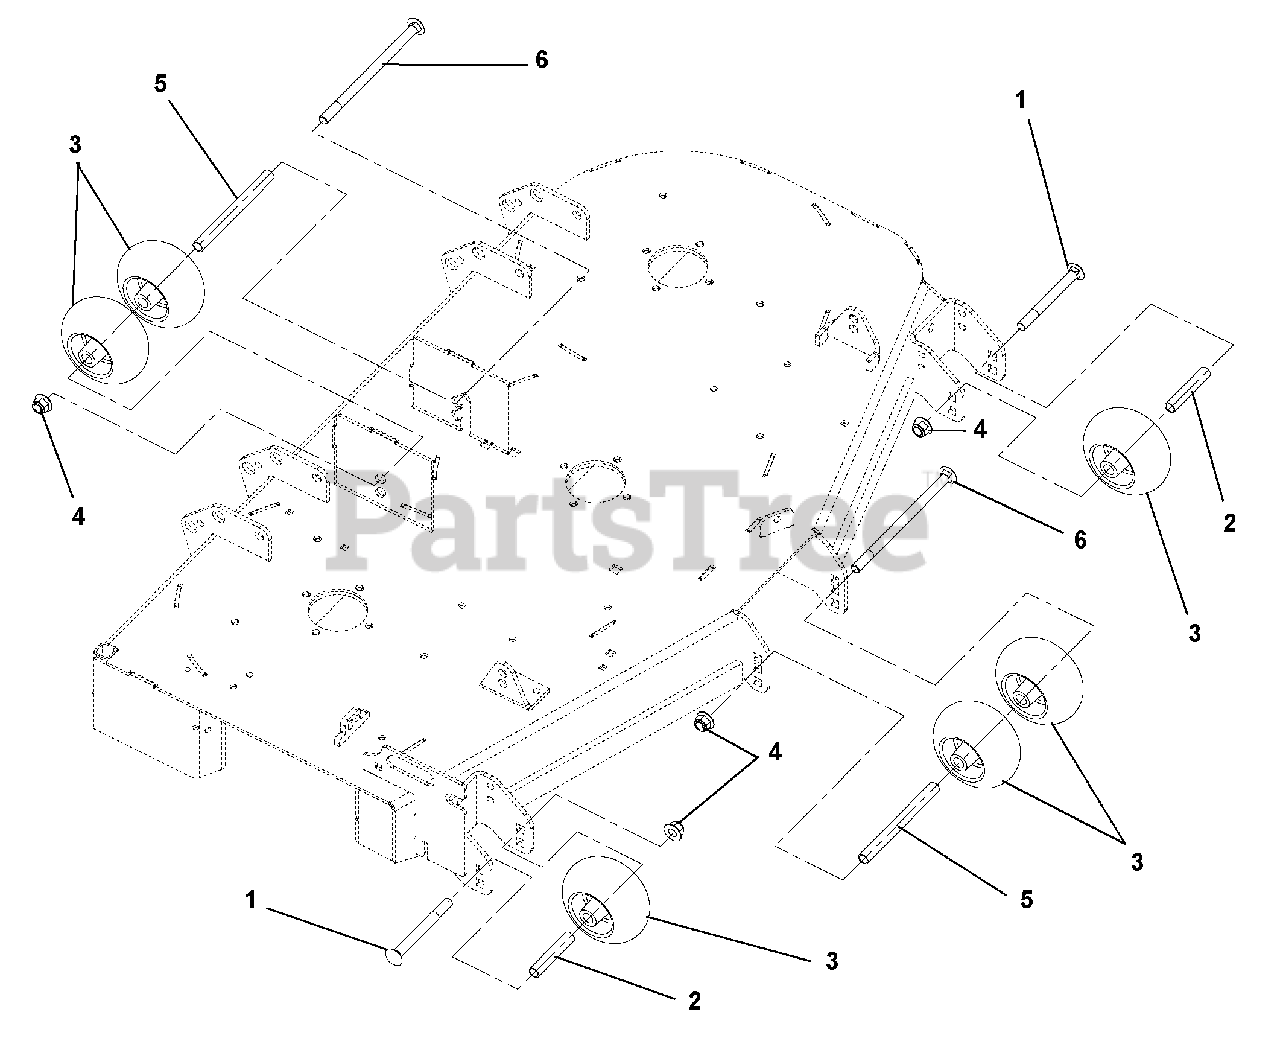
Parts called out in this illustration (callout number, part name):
1	BLT-RDHDSQNK .50-13X5.00 GR5YZ
2	SPACER, .510X.625X3.35
3	WHEEL, ANTI SCALP
4	NUT-LK-NYL-FLG .50-13 YWZC
5	SPACER, .510X.625X6.50
6	BLT-RDHDSQNK .50-13X8.50 G5YZ
